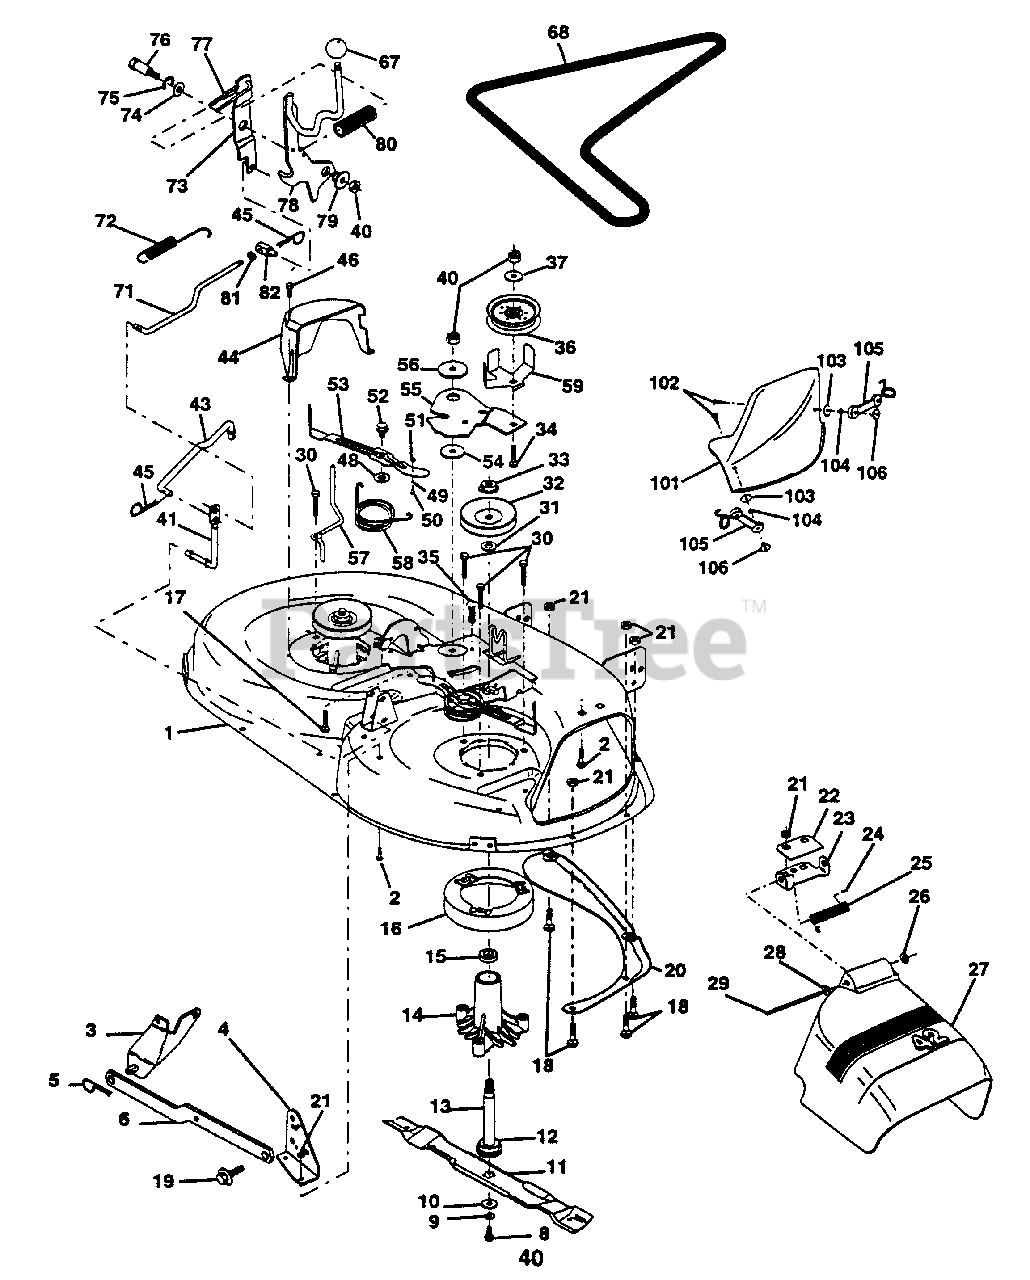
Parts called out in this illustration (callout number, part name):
1	Deck Asm MWR 42" weldment
2	Bolt Rdhd Sqnk 5/16-18unc X3/4
3	Bracket Asm Fr Sway Bar 38/42
4	Bracket Asm Deck 42" sway Bar
5	Retainer Spring
6	Arm Suspension Rear
7	Locknut-hex W/ins 5/16-18unc P
8	Bolt 318 - 24 X 1.25 Gr 8
9	Washer Lock Hvy 3/8
10	Washer Hard Blade Mower Vented
11	Blade Mower Mulching 42"
12	Bearing Ball #6024 (Mandrel)
13	Shaft Asm W/lower Bearing
14	Housing Mandrel Vented
15	Bearing Ball Mandrel
16	Stripper Mower Vented
17	Bolt Rdhd Sqnk 3/8-16 X 1-1/4
18	Bolt Rdhd Sqnk 5/16-18 X 5/8
19	Bolt Shoulder
20	Baffle Vortex 42
21	Nut Crown Lock 5/16-18 Unc
22	Stiffener Bracket 42" deck
23	Bracket Deflector Mower 42"
24	Cap Sleeve 80x 112 Blk Mower
25	Spring Torsion Deflector 2 52
26	Nut Push Phos & Oil
27	Shield Deflector Mower 42" Blk
28	Washer 11/32 X 5/8 X 16 Ga
29	Rod Hinge 42" 6 75 Wlg
30	Screw Thdrol Hex Head Zinc Mwr
31	Washer Spacer Mower Vented
32	Pulley Mandrel 42"
33	Nut 9/16 Toplock Flng Oil Dip
34	Bolt Rdhd 3/8-16uncx 1-3/4 Gr5
35	Fastener Christmas Tree
36	Pulley Idler Flat 3 060
37	Washer 13/32 X 13/16 X 16
40	Nut Lock Hex W/Ins 3/8-16 Unc
41	Rod Pivot W/nibs
43	Rod Clutch Secondary W/nibs
44	Guard Mandrel LH Black
45	Spring Retainer 1" Zinc/cad
46	Screw Hex Thd Cut 1/4-20x5/8 T
48	Washer Hardened Smaller
49	Roller Asm Cam Follower 42" dec
50	Bolt Shldr 10-24 Zinc Gr 5 42"
51	Nut Lock #10-24 Unc
52	Bolt Shoulder 5/16-18 Unc Blkz
53	Arm Asm Pad Brake
54	Washer Hardened
55	Arm Idler 42" mower LT/YT
56	Spacer Retainer Pm Mower
57	Keeper Belt LH Front
58	Spring Torsion Brakes
59	Guard TUV Idler
67	Knob Rd 1/2-13 Plstc Thds Blk
68	V-Belt Mower 42"
71	Rod Clutch Primary 38/42
72	Spring Return
73	Arm Clutch Secondary
74	Washer 25/32 X 1-5/8 X 16 Ga
75	Ring Klip #t5304-75
76	Bolt Shoulder 3/8-16 Unc 1 4.4
77	Keeper Spring 4 000
78	Arm Asm Clutch Primary
79	Bushing 747 Od X 794 Lg Brass
80	Spring Clutch Mower 2 750 Zinc
81	Nut Hex Jam 3/8-16
82	Trunnion Adj 94
83	Washer Sintered
84	Keeper Belt Idler Fixed
85	Bolt Carriage 3/8-16 x 2-1/2 Gr. 5
92	Nut Crownlock 3/8-16 Unc
101	Cover Mulching 42" Black
102	Screw
103	Washer #10
104	Washer Lock #10
105	Latch Asm Bagger
106	Nut Weld
